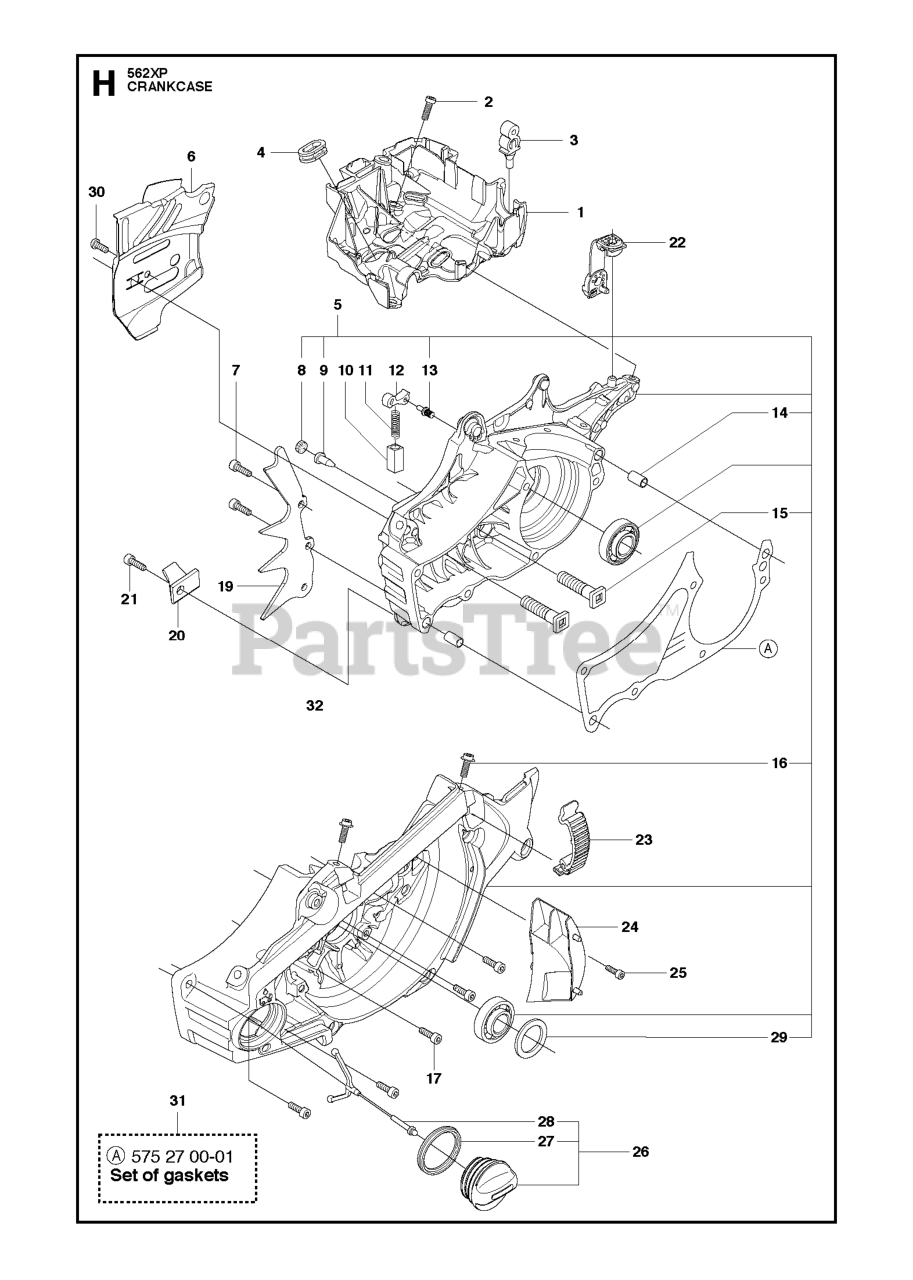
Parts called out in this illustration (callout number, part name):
1	CARBURETTOR AREA BASE
3	SUPPORT
5	CRANKCASE
6	CHAIN GUIDE PLATE
7	SCREW MC6S 5X16
8	PLUG
9	VALVE-CHECK (DUCKBILL)
11	LOCK SPRING
13	PIN
14	SLEEVE
15	BAR BOLT
16	SCREW IHSCM
17	SCREW IHSCM
20	CHAIN CATCHER
22	DEFLECTION LIMITER
23	CLIP GRAY
24	AIR NOZZLE
25	SCREW IHSCM
26	TANK CAP
27	SEALING
28	TANK LOCK
29	RADIAL SEAL
31	RP GASKET KIT
